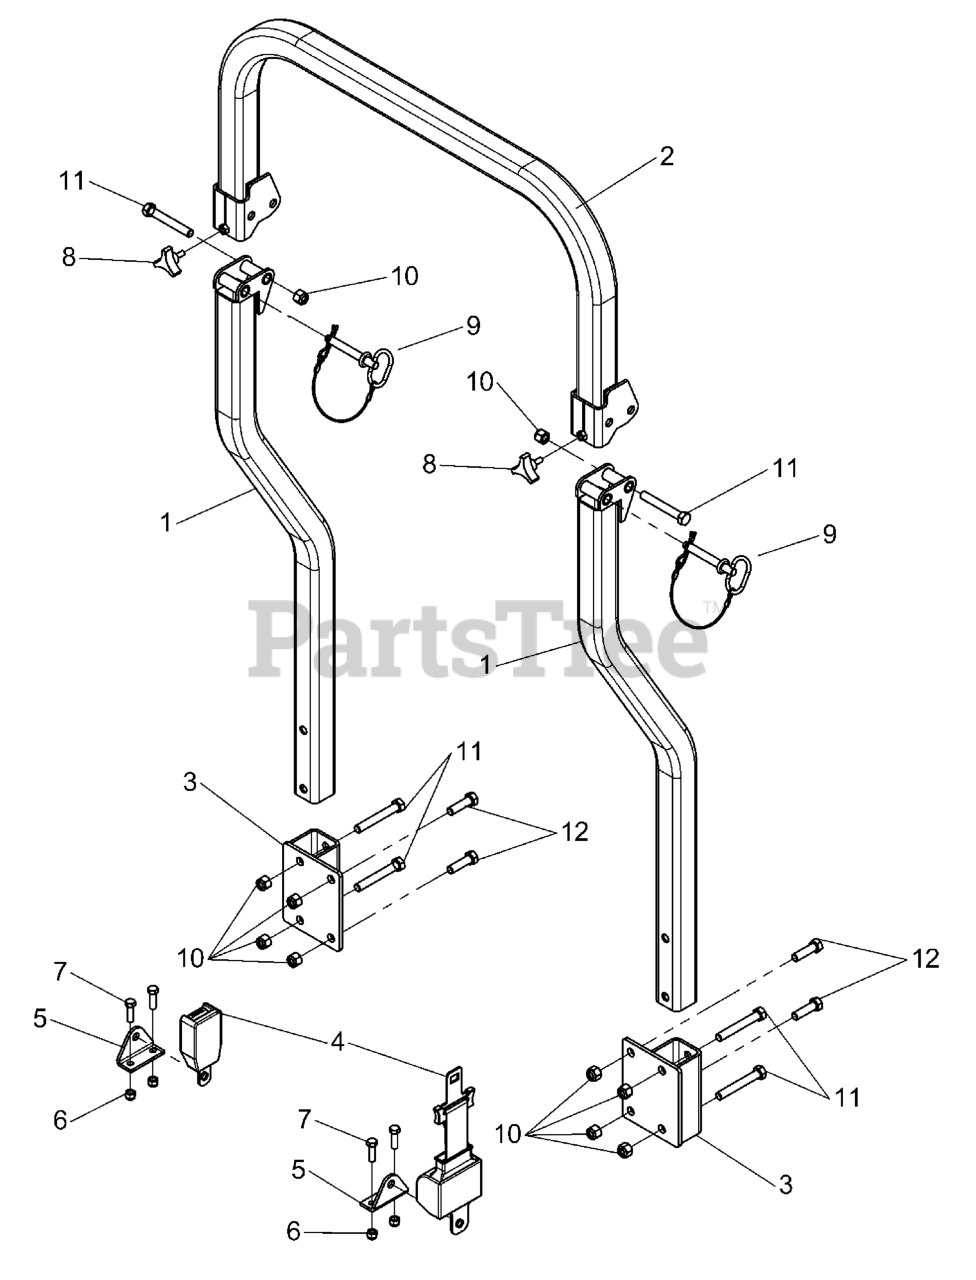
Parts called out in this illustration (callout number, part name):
1	ROPS POST
2	ROPS TOP LOOP
3	ROPS SOCKET
4	SEAT BELT, COMPLETE W/ HARDWARE
5	MOUNT, SEAT BELT
6	NUT, 3/8-16 HEX NYLON LOCK
7	BOLT, 3/8-16 X 1-1/4" GD5 CZ
8	KNOB, PLASTIC, 5/16-18 X 3/4"
9	PIN, HITCH, .50 X 3.25 W/ LANYARD
10	NUT, 1/2-13 HEX NYLON LOCK
11	BOLT, 1/2-13 X 3-1/2, HEX HD, GD5, CZ (SV)
12	BOLT, 1/2-13 X 1-3/4 GD5 CZ
